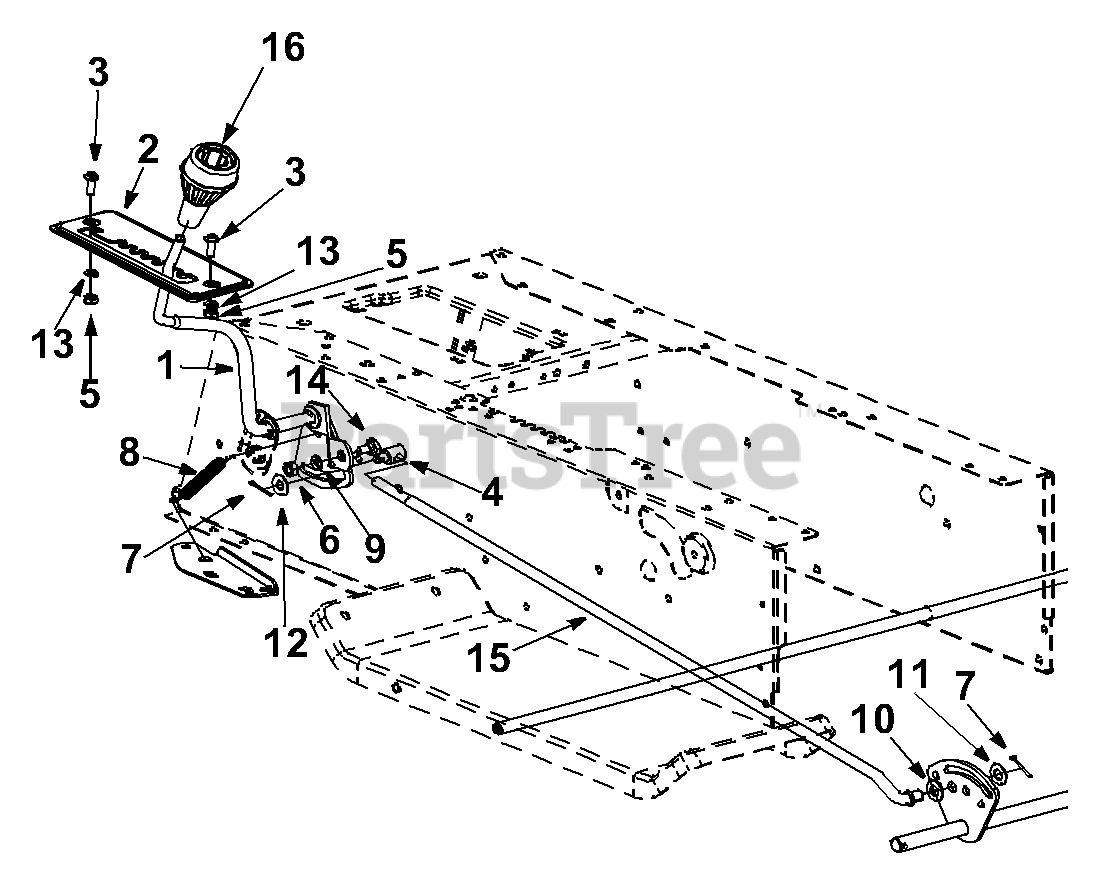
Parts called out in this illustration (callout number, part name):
1	Speed Selector Lever Ass'y
4	Ferrule 3/8-24 Thd.
5	Hex Nut 1/4-20 Thd. (Gr. 5)
6	Hex Nut 5/16-18 Thd. (Gr. 5)
7	Cotter Pin 3/32" Dia. x 1.0"
8	Spring .38" O.D. x 3.18" Lg.
9	L-Wash. 5/16" I.D.
10	Fl-Wash. .53" I.D. x .93"
11	Fl-Wash. .469" I.D. x .88"
12	Fl-Wash. .385" I.D. x 7/8"
13	L-Wash.1/4" I.D.
14	Shoulder Bolt
15	Speed Control Rod
16	Shift Knob
